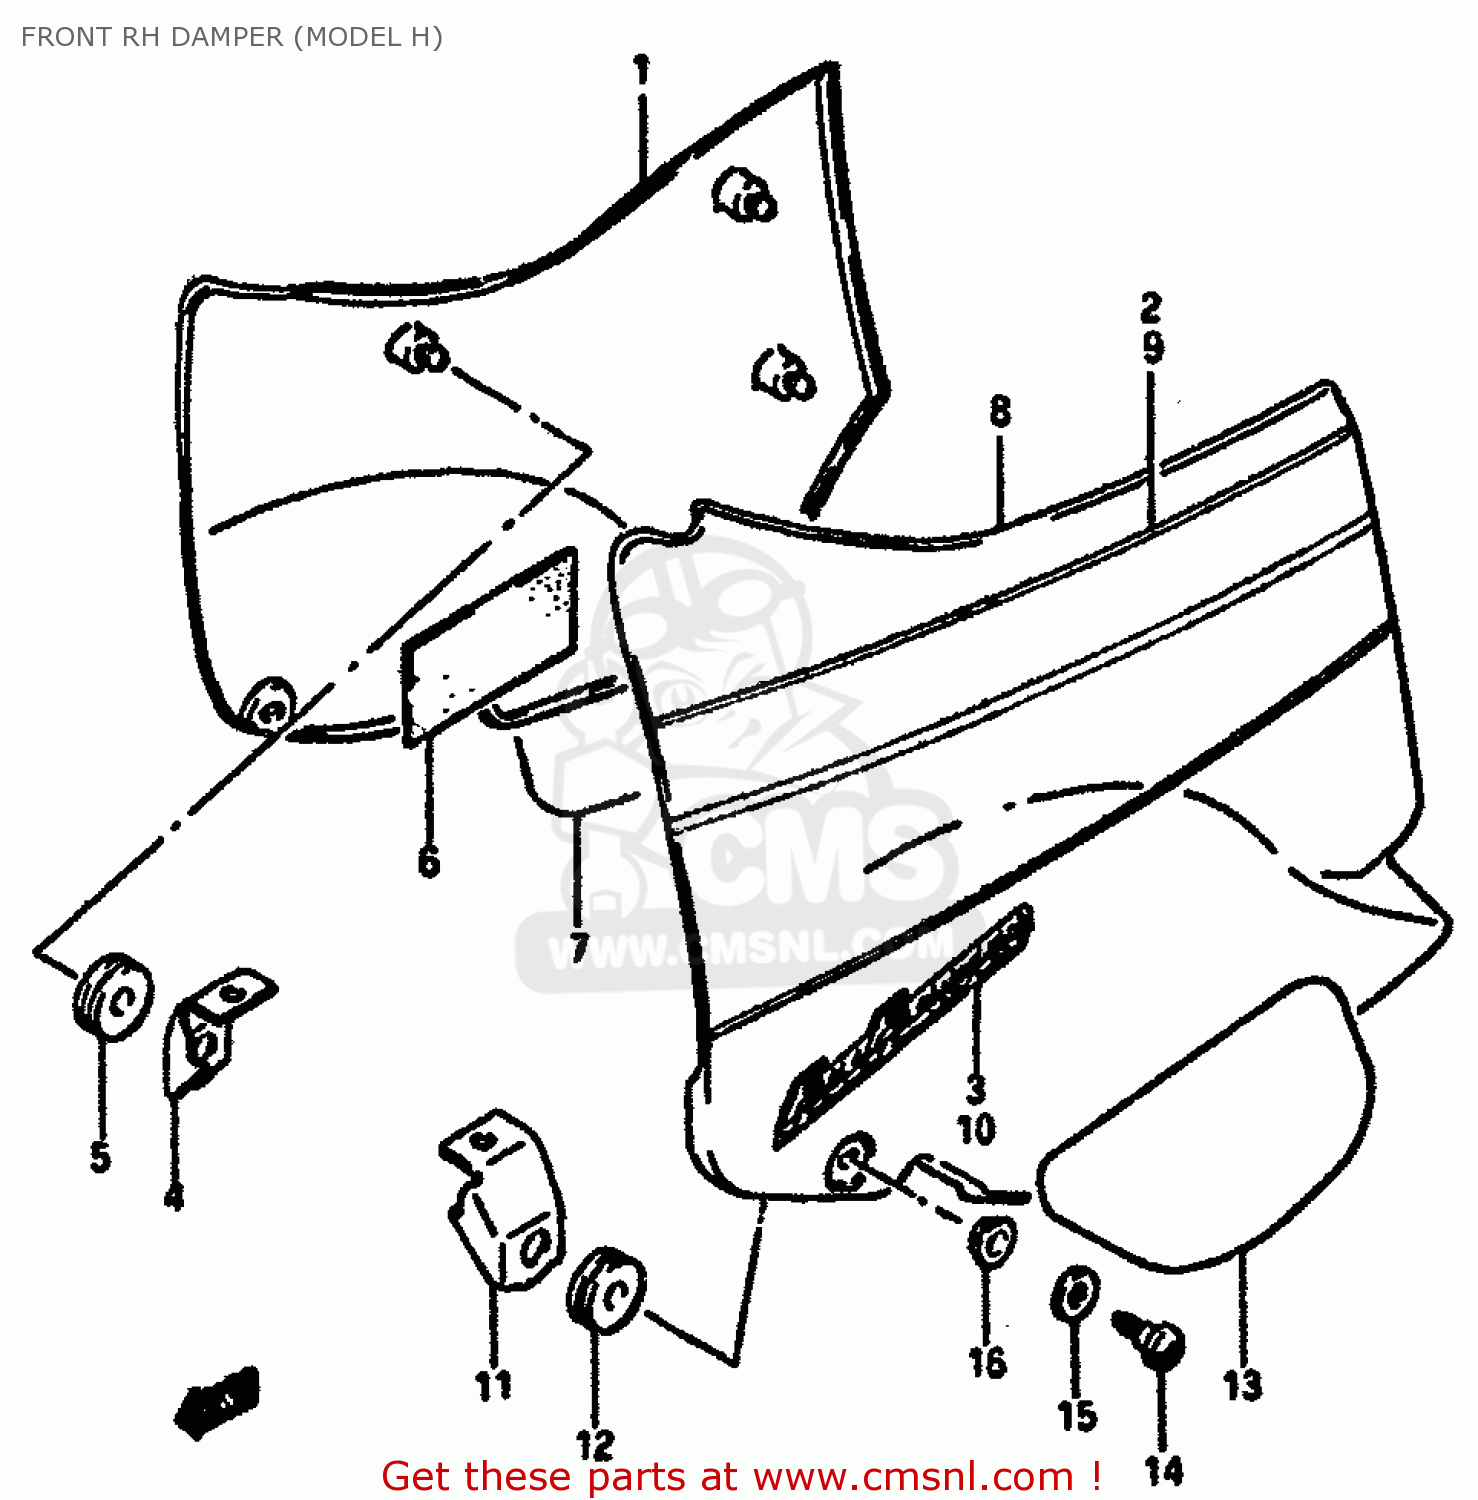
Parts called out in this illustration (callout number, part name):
1	COVER,FRAME,RIGHT
2	TAPE SET,FRAME COVER,RIGHT
3	EMBLEM
4	HOLDER,FRAME COVER,RIGHT
5	CUSHION
6	RUBBER,FRAME COVER,RIGHT
7	PROTECTOR,FRAME COVER
8	COVER,FRAME,LEFT
9	TAPE SET,FRAME COVER,LEFT
10	EMBLEM
11	HOLDER,FRAME COVER,LEFT
12	CUSHION
13	PROTECTOR,FRAME COVER LH
14	SCREW(6X23)
15	WASHER
16	CUSHION
